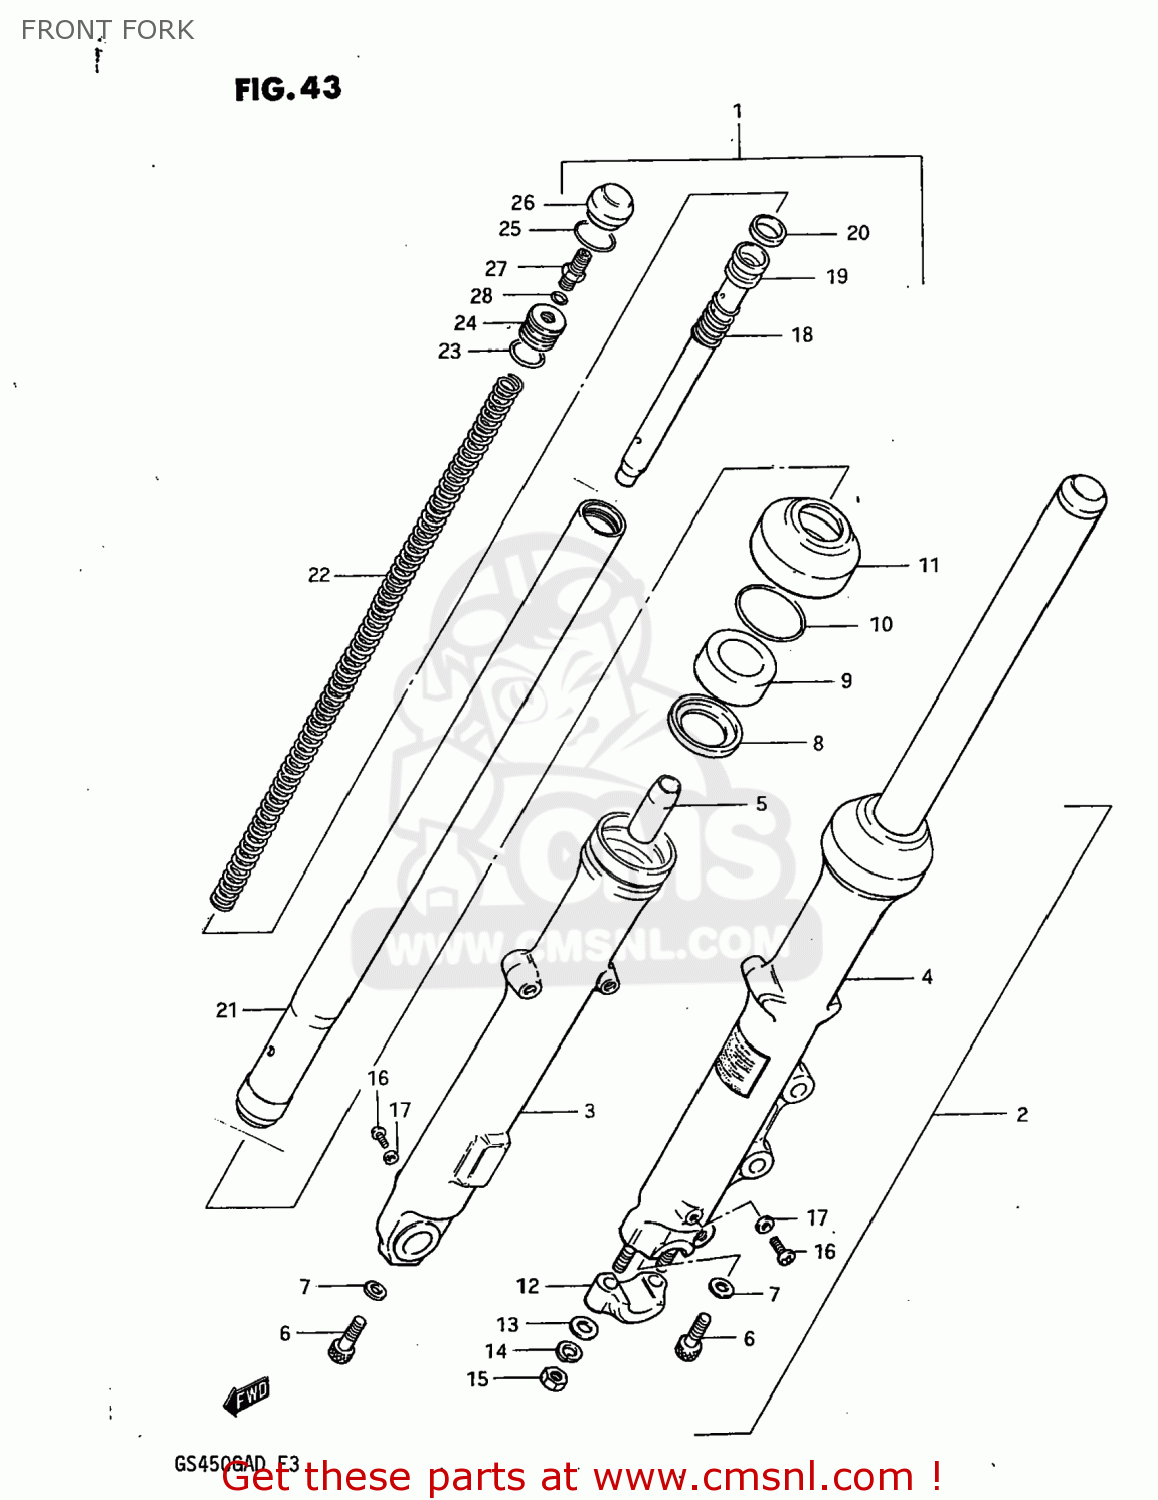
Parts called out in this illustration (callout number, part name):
1	DAMPER ASSEMBLY,RIGHT
2	DAMPER ASSEMBLY,LEFT
3	TUBE,FORK,OUTER,RIGHT
4	TUBE,FORK,LEFT,OUTER
5	PIECE,OIL LOCK
6	BOLT(8X27)
7	GASKET (NAS)
8	SPACER,OIL SEAL
9	OIL SEAL,FRONT FORK
10	RING,OIL SEAL STOPPER
11	DUST SEAL
12	HOLDER,AXLE
13	WASHER
14	LOCK WASHER
15	NUT
16	SCREW 4X6
17	GASKET (NAS)
18	SPRING,REBOUND
19	CYLINDER,FRONT FORK
20	RING,PISTON
21	TUBE,FORK,INNER
22	SPRING
23	O RING
24	SEAT,SPRING
25	RING,STOPPER
26	CAP,FRONT FORK
27	VALVE,AIR
28	O-RING
